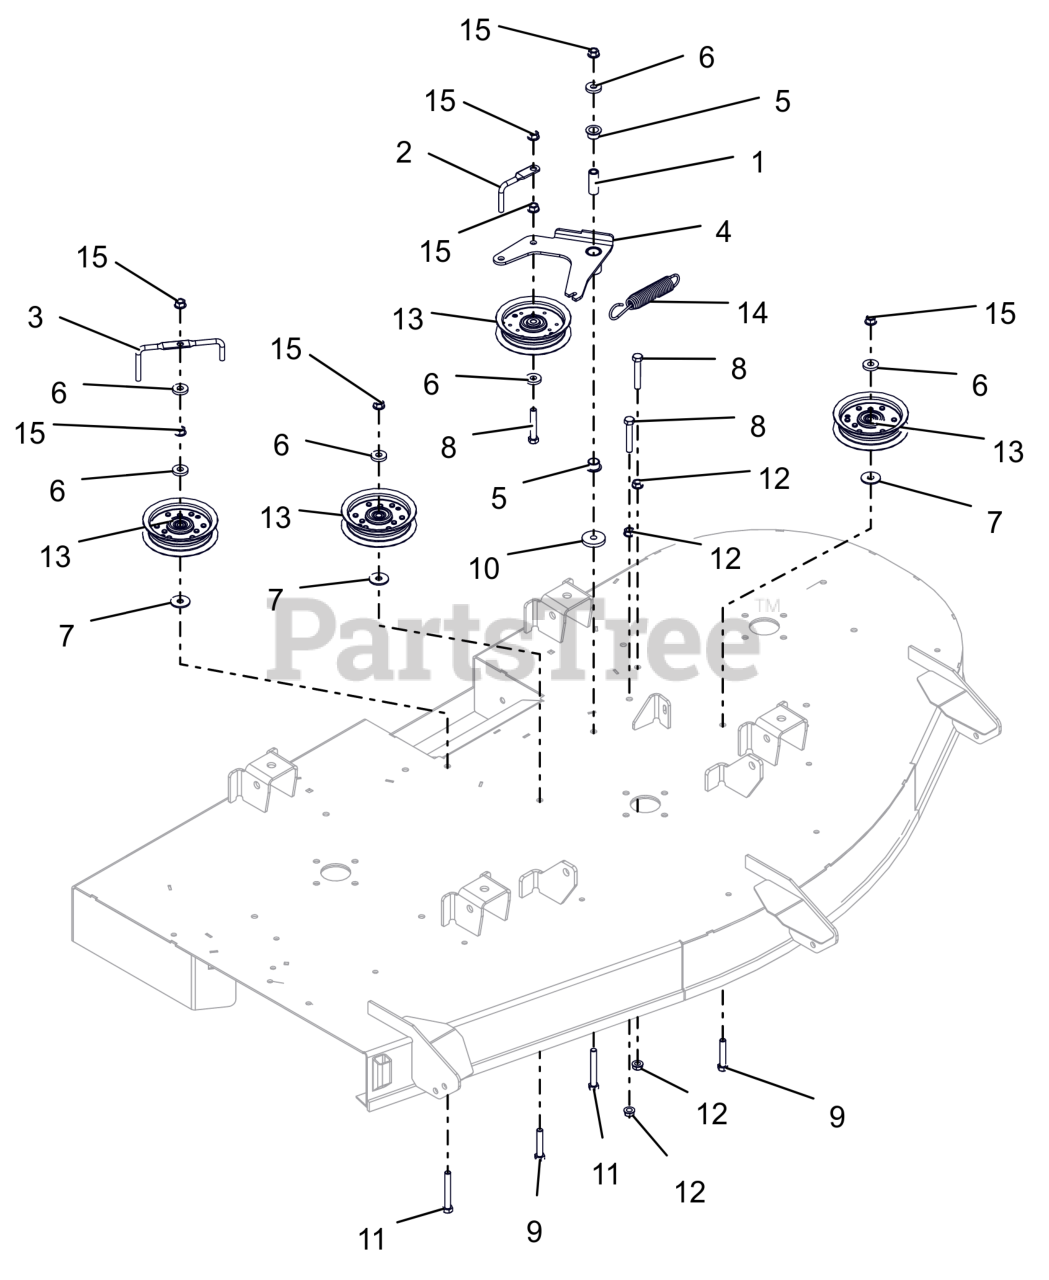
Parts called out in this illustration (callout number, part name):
1	SPACER, .375IDX.625ODX1.66 PM
2	WIREFORM, BELT FINGER
3	WIREFORM, BELT FINGER
4	WLDMT, IDLER ARM-42"
5	BSHG-FLG, .625X.750X.500X1.00
6	WSHR, FLT .406X1.00X.188 ZCC
7	WSHR FL STL .406X1.25X.10ZC120
8	BLT,HEX .38-16X2.25 G5 ZCC
9	BLT,HEX .38-16X2.00 G5 ZCC
10	WSHR, FLT .406X1.50X.245 ZCC
11	BLT, HEX .38-16X2.75 G5 ZCC
12	NUT, SPNLK-FLG .38-16 G5 ZCC
13	ASM, IDLER 4"
14	SG-TENS .135X.98X6.0 WLD 62
15	NUT-LK-CTR-FLG .375-16 GF ZCC
